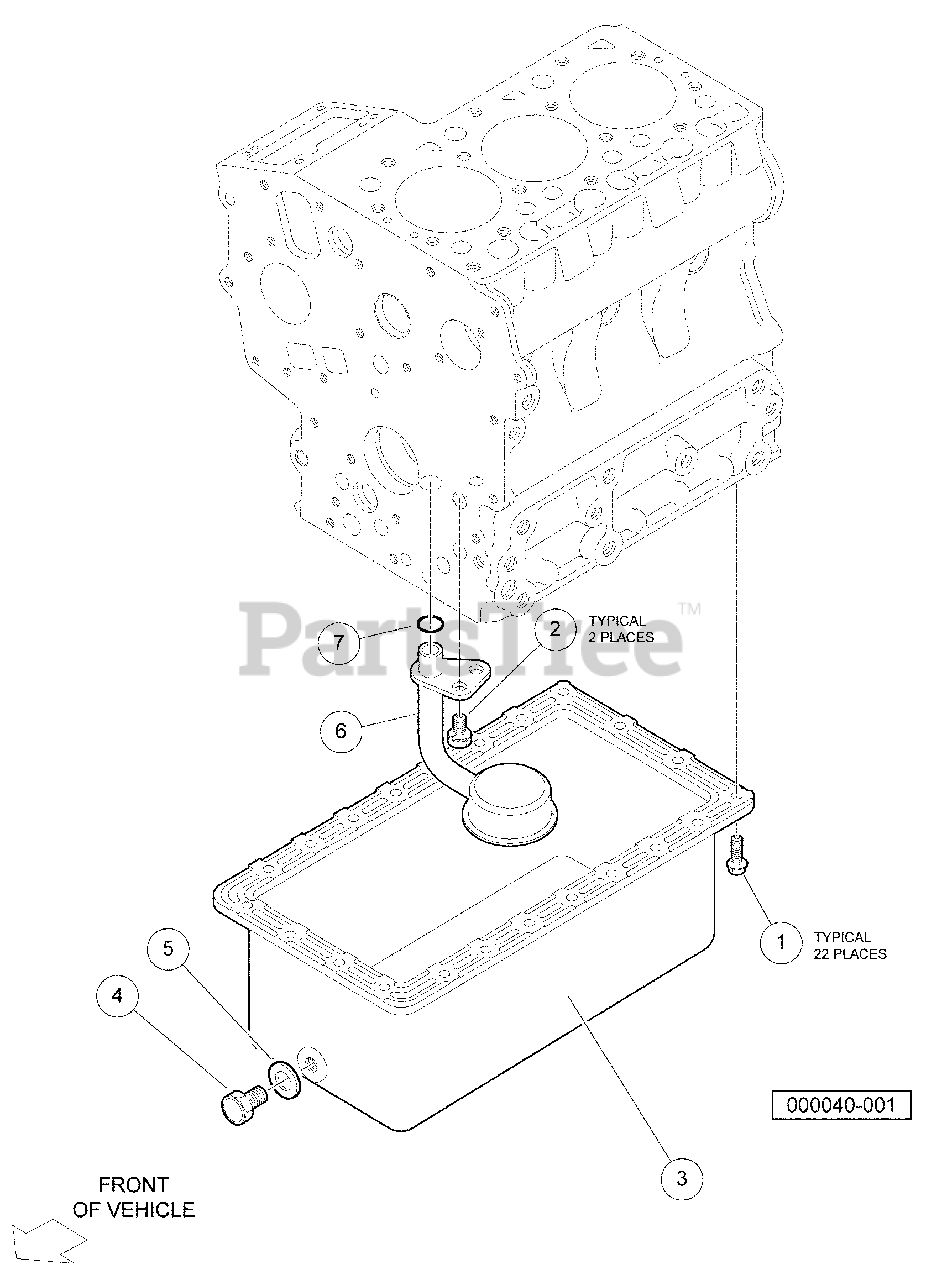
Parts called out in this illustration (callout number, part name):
1	Bolt, M6 X 1 X 14
2	Bolt, M8 X 1.25 X 15
4	Plug, Drain, M12 X 14
5	Gasket, 20 X 13
6	Filter, Oil, Pick Up
7	O Ring, 20 X 17
